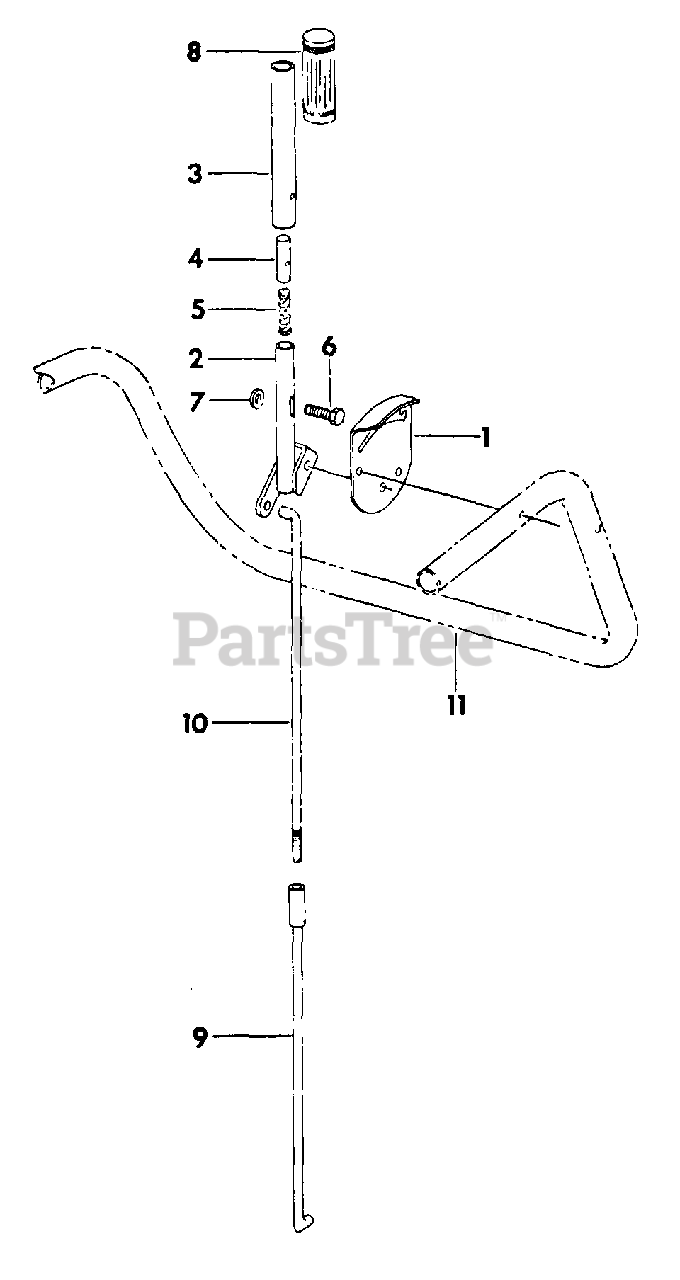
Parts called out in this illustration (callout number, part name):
1	BRACKET, CONTROL SUPPORT
3	HANDLE, SHIFT LEVER
5	SPRING
6	SCREW, 1/4-20 X 1-1/2 HEX-HD CAP
8	GRIP, HANDLE
9	ROD, CONTROL ADJUSTING LOWER
10	ROD, CONTROL ADJUSTING UPPER
11	BAR, HANDLE
